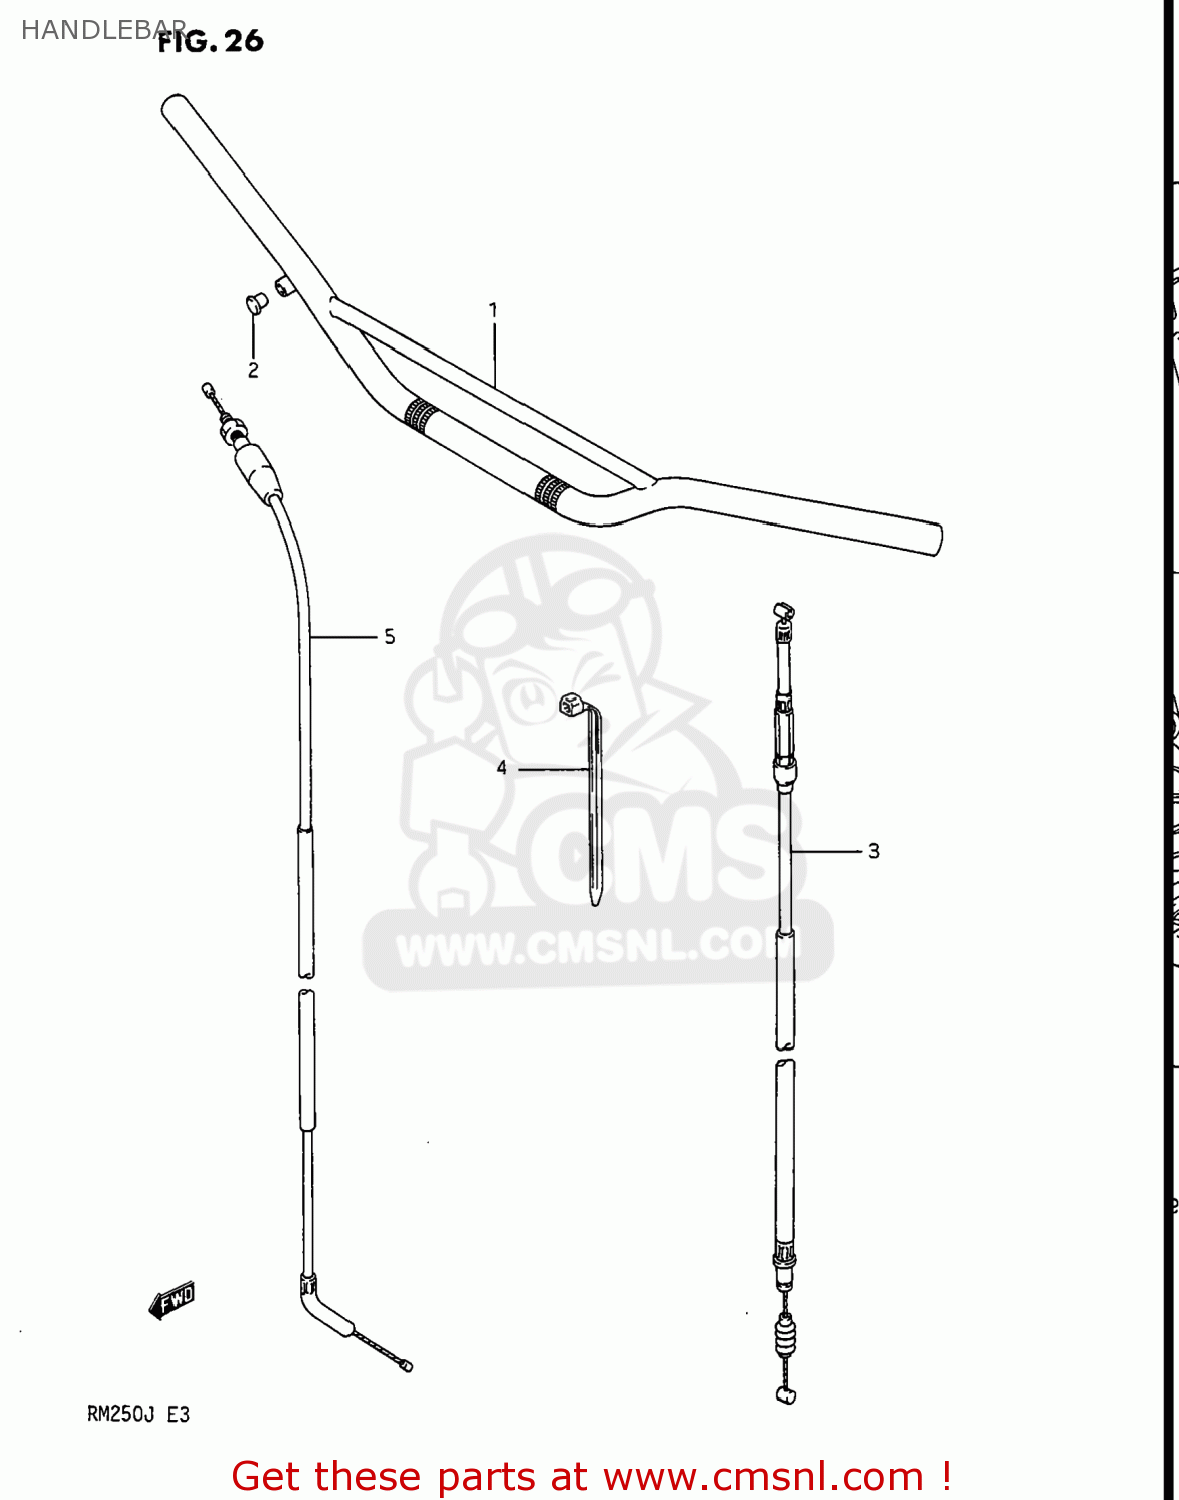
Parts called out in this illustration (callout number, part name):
1	HANDLEBAR
2	CAP(OD:14)
3	CABLE ASSEMBLY,CLUTCH
4	CLAMP(L:165)
5	CABLE ASSEMBLY,THROTTLE
